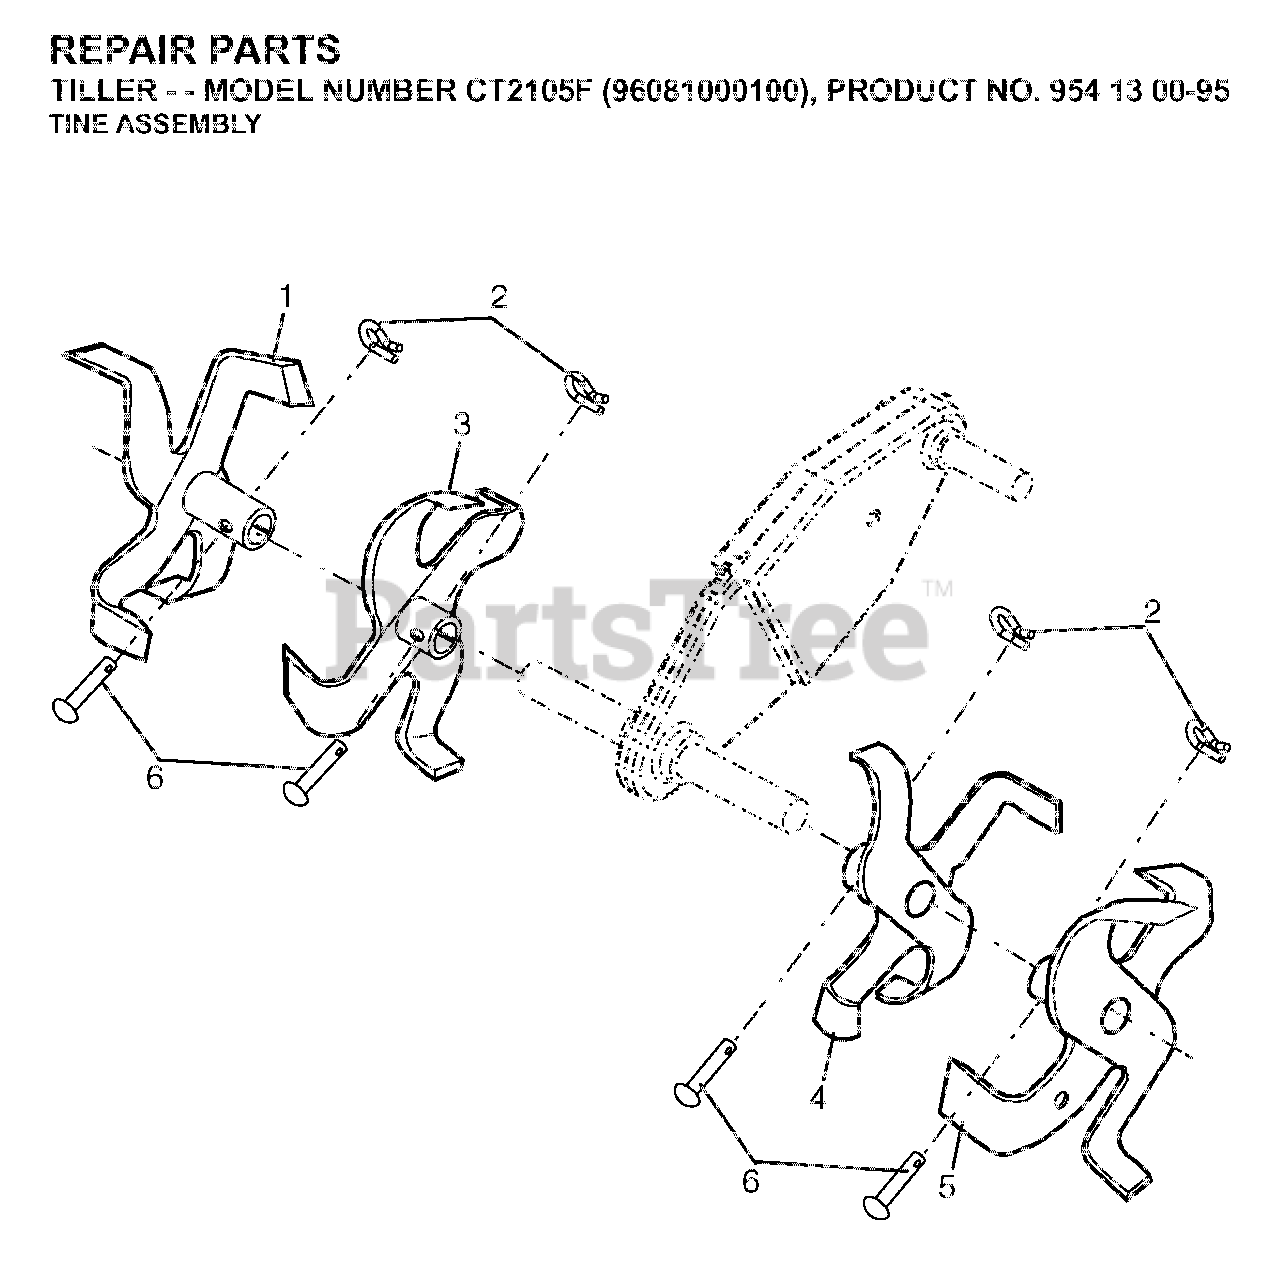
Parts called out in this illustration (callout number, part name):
1	RP TINE
2	SPRING RETAINER
3	RP TINE
4	RP TINE
5	RP TINE
